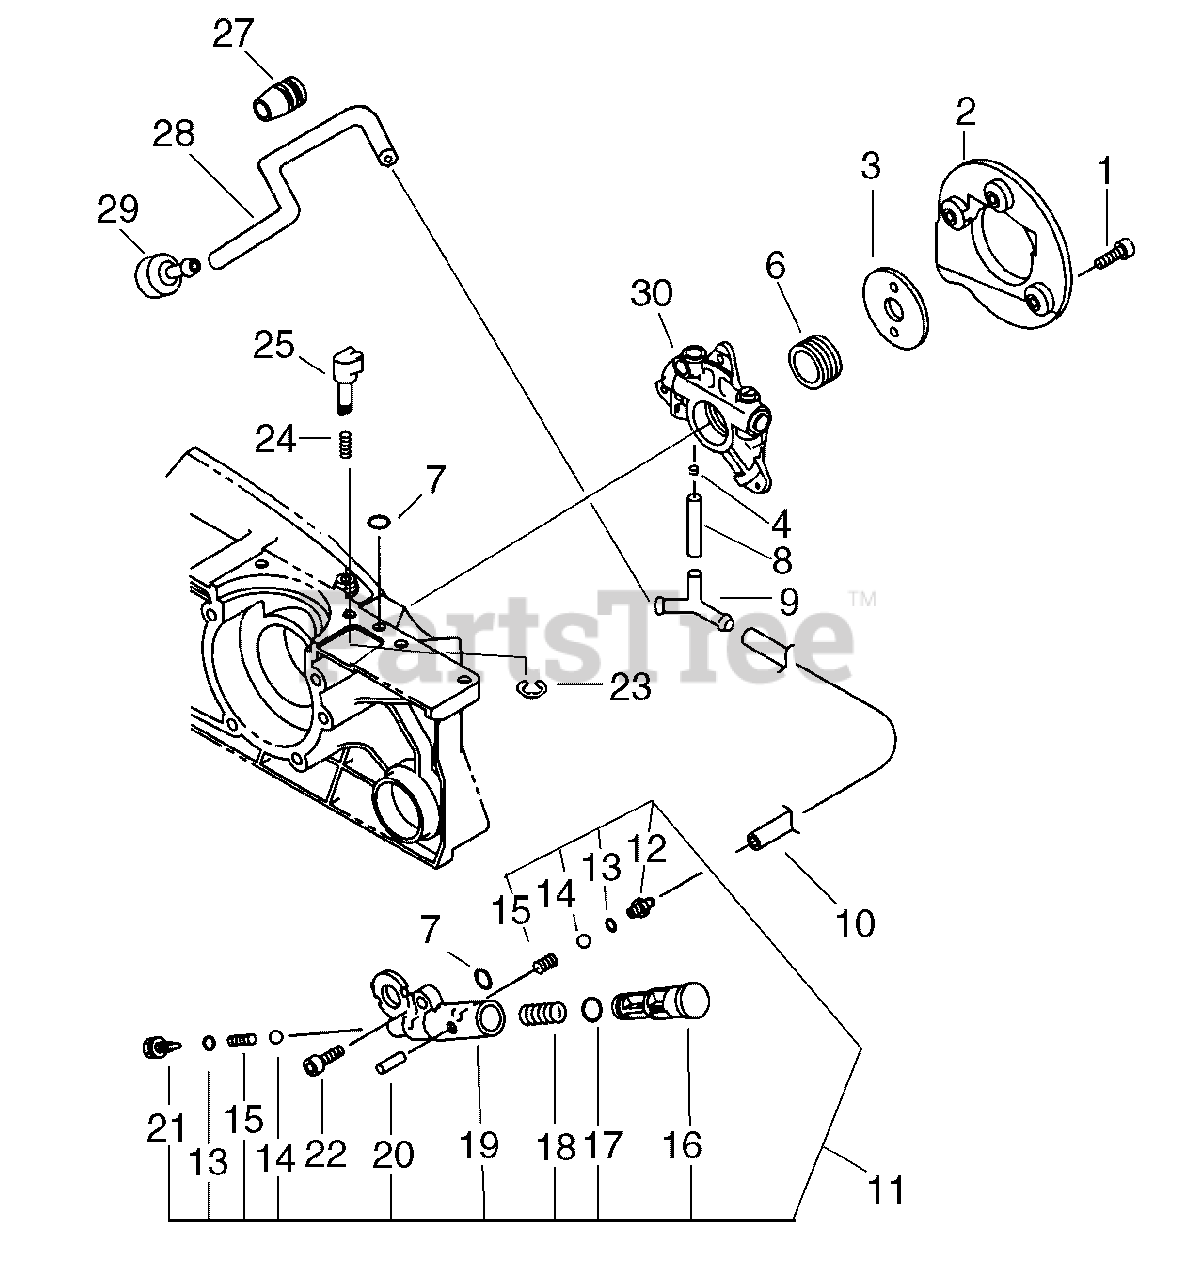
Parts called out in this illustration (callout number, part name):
1	SCREW - 4X14
2	COVER, OIL PUMP
4	CLIP - 6.5
6	GEAR - WORM
7	O-RING - 3
8	PIPE - 3X6X20 -- BLACK
9	CONNECTOR, PIPE
10	PIPE - 3X6X210 -- BLACK
11	MANUAL OILER ASSY
14	VALVE, BALL
16	PISTON, MANUAL
17	O-RING - 7
19	BODY, OIL PUMP
20	PIN - SPRING -- 2X16
21	ADAPTER, OIL PUMP
22	SCREW - 5X20
23	RING, RETAINING - 3
25	DIAL, AUTO-OILER
28	PIPE - OIL
29	FILTER, OIL
30	AUTO-OILER ASSY
